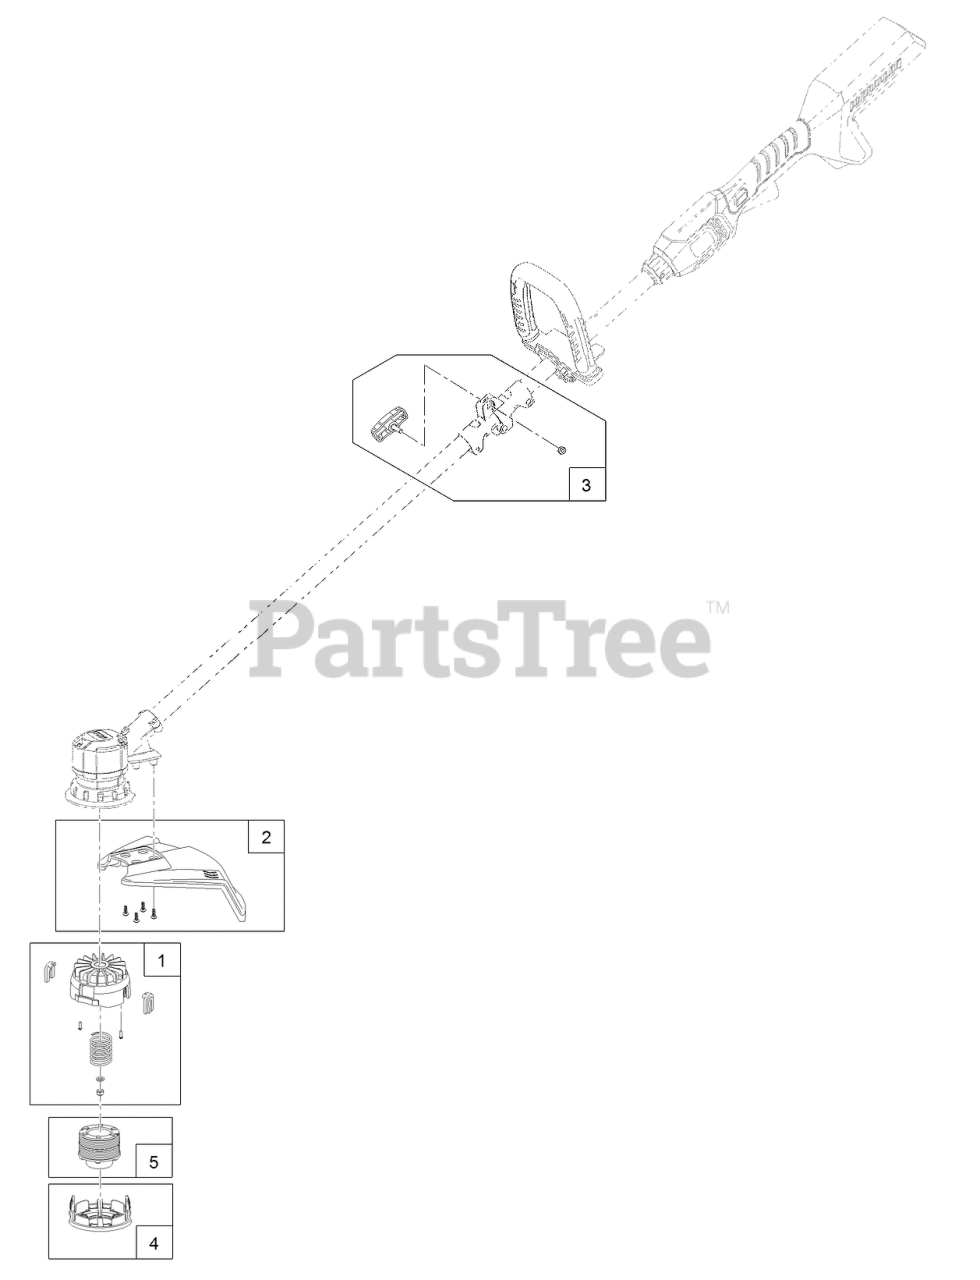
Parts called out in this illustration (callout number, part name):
1	HEAD-FEED, BUMP
2	GRASS SHIELD ASM
3	SHAFT CONNECTION HARDWARE KIT
4	RETAINER-CAP, SPOOL
5	3-PK DUAL-LINE SPOOL
